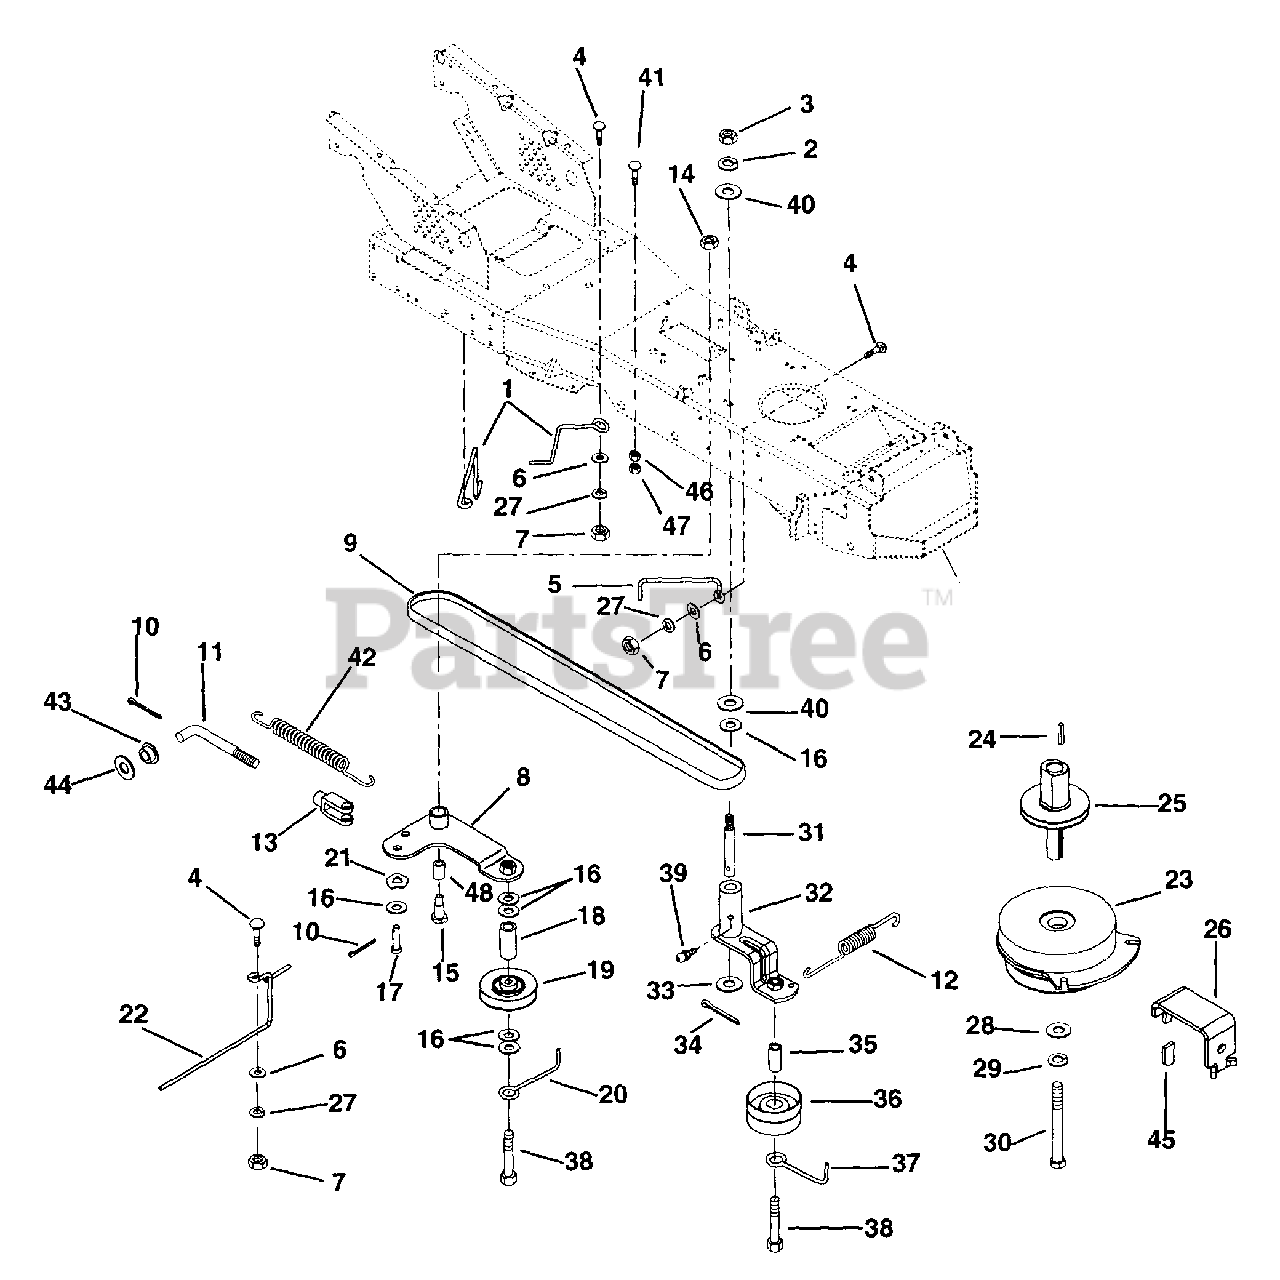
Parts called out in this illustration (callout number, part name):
1	Belt Finger
2	Washer-Locking .38 x .094
3	Nut-Hex .38-16
4	Bolt-Round Head Square Neck .31-18 x .75
5	Belt Finger
6	Washer-Flat-Steel .344 x .688 x .065
7	Nut-Hex .312-18
8	Idler Pivot Arm
10	Pin-Cotter .09 x .75
12	Spring-Extension
13	Yoke .31-24 x 2.250
14	Nut Locking .38-16
15	Bolt-Shoulder .38-16 x 1.25
16	Washer-Flat .390 x .75 x .125
17	Pin-Clevis .312 x .822
19	Idler-V 3 x .38
20	Belt Finger
21	Wave Washer
22	Belt-Finger-Center
23	Clutch-Electric
24	Key-Square .25 x 1.25 x .25
25	Shaft-Sheave Ext.
26	Anchor-Clutch
27	Washer-Locking-Heavy .312 x .097
28	Washer-Flat-Steel .463 x 1.375 x .25
29	Washer-Locking-Heavy .438 x .133
30	Bolt-Hex .44-20 x 5.50 Grade 5
31	Shoulder Stud
32	Arm-idler Pivot
33	Washer-Flat-Steel .520 x .827 x .062
34	Pin-Cotter .18 x 1.25
35	Tube .380 x .625 x 1.620
36	Idler-Flat 3.25 x .38
37	Finger-Belt
38	Bolt-Hex .38-16 x 3.50 Grade 5
39	Fitting-Lube .25-28 x .256
40	Washer-Flat-Steel .438 x 1.0 x .083
41	Bolt-Round Head Square Neck .31-18 x 1.00
42	Spring-Tension .105 x .85 x 5.00
43	Bushing-Flange .320 x .620 x .312
44	Washer-Flat-Steel .505 x .880 x .072
45	Grip .062 x .375 x .750
46	Nut-Locking-Nylon .312-18
47	Nut-Locking-Center .312-18
48	Spacer-.344 x .500 x .75
